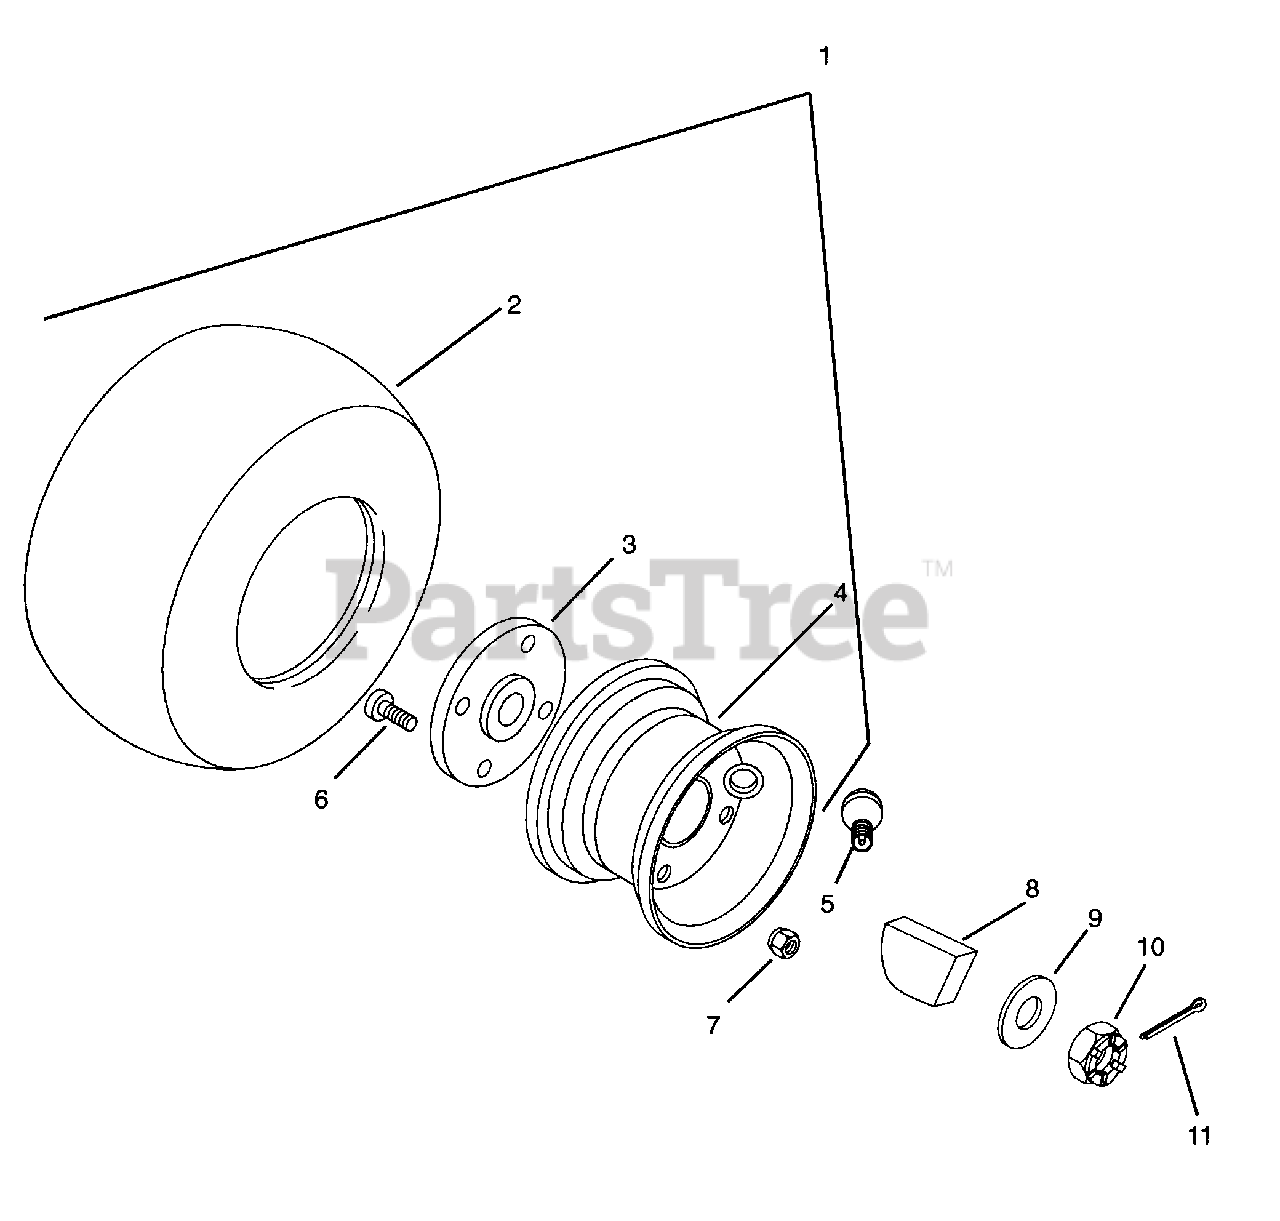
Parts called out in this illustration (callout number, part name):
1	Tire/Wheel Assembly
2	Tire/Wheel Assembly 18 x 8.50-8
3	Assembly, Hub
4	Assembly, Rim
5	Valve Stem Assembly
6	Bolt .50-20 x 1.25
7	Nut-Hex .50-20
8	Key, Square 3/16 x .750
9	Washer-Flat-Steel .813 x 1.370 x .100
10	Nut, Hex 3/4-28
11	Pin-Cotter .06 x 1.00
